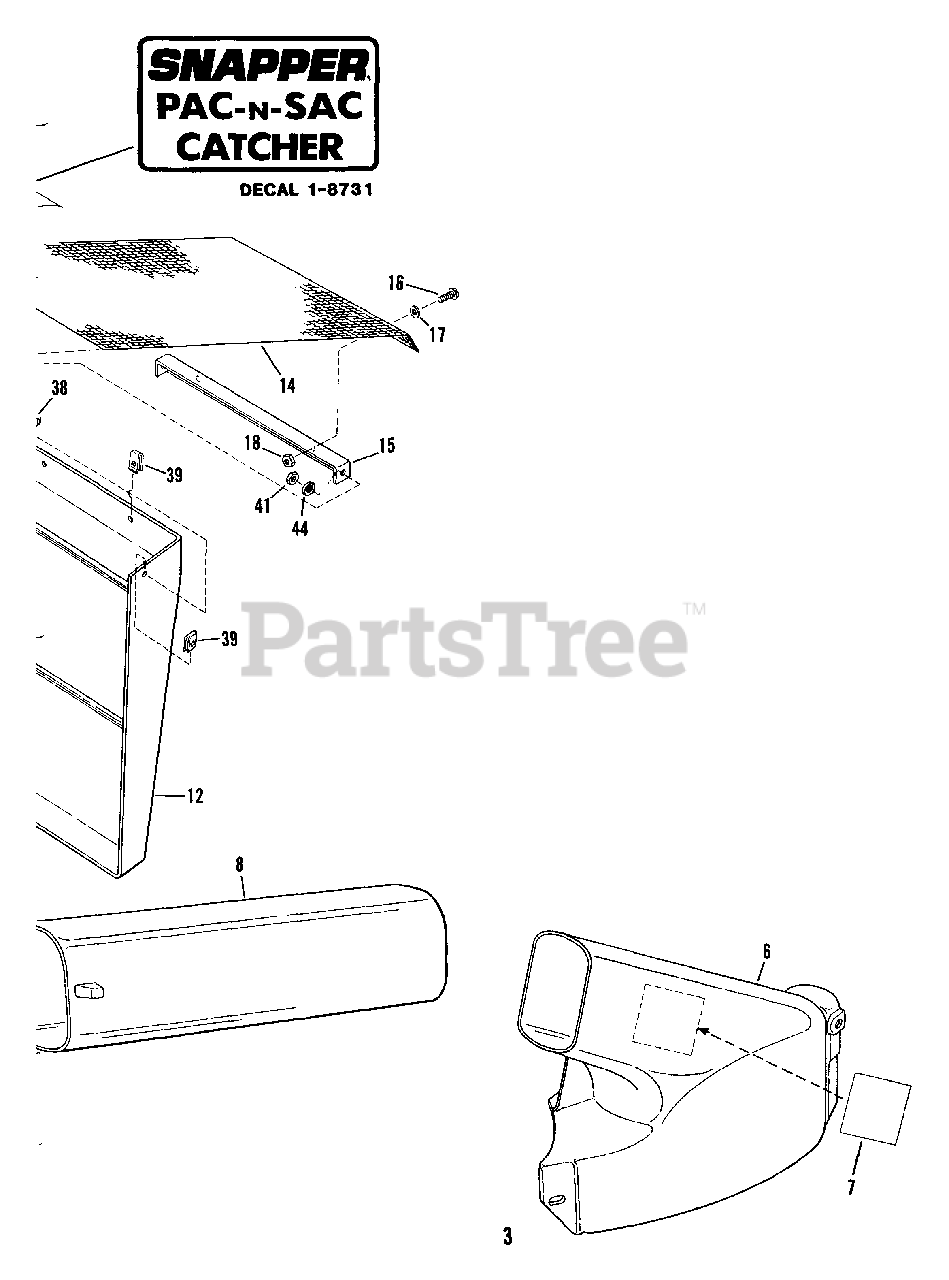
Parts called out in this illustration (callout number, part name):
6	ASSEMBLY, Adapter
7	DECAL, CPSC
8	GRASS TUBE, Lower
14	SCREEN
15	ANGLE, Screen
16	SCREW, #10 - 24 x 3/4" RH Machine
17	WASHER, 3/16" Flat
18	NUT, #10 - 24 Hex Lock
38	MACHINE SCREW, #10 - 16 x 3/4" Slotted
39	NUT, #10 - 16 Clip
41	NUT, 5/16 - 18 Hex
44	WASHER, 5/16 Internal Tooth Lock
